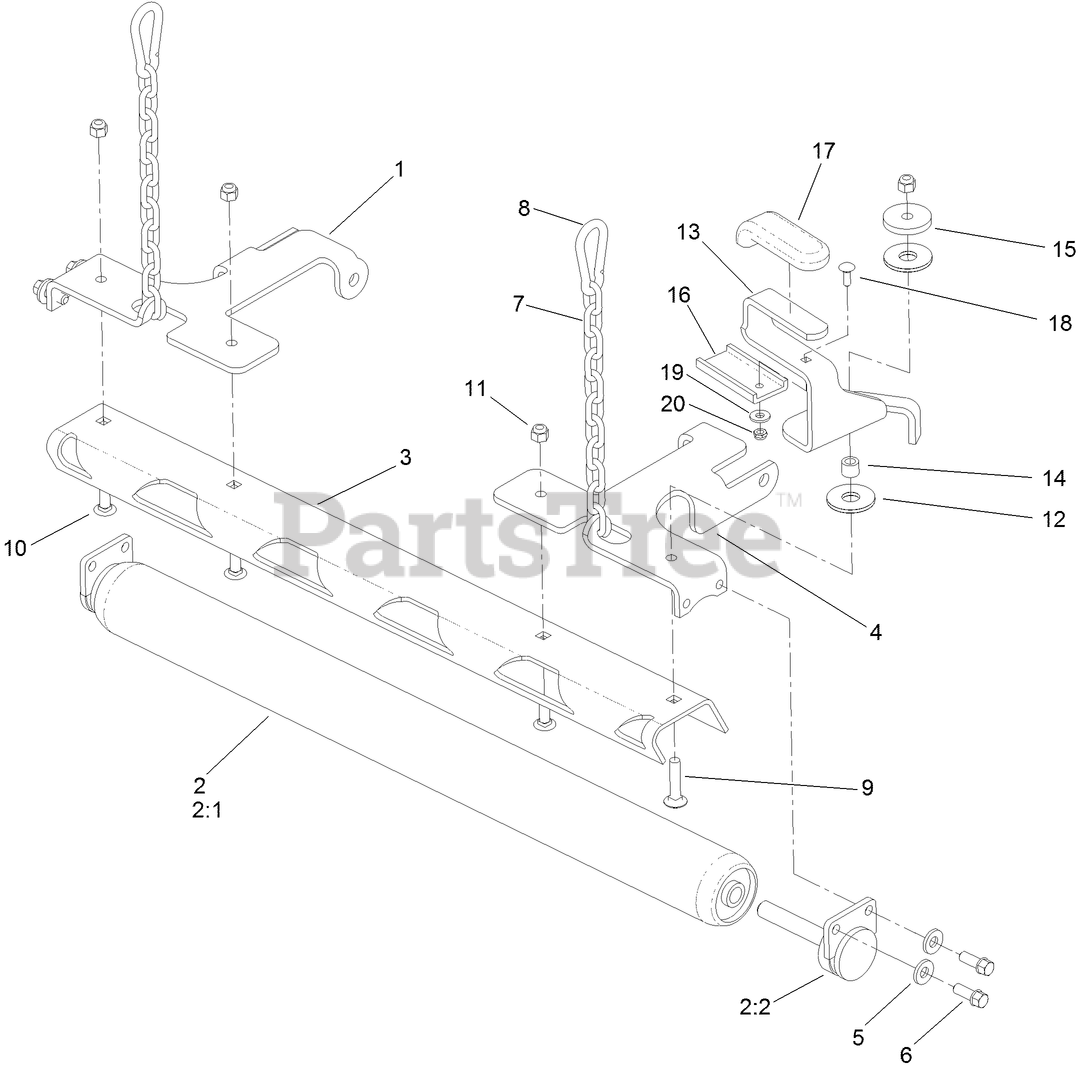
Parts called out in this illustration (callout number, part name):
1	MOUNT-ROLLER, LH
2	ROLLER ASM
2:1	ROLLER-STRIPER
2:2	HUB ASM
3	SCRAPER-ROLLER
4	MOUNT-ROLLER, RH
5	WASHER-BELLEVILLE
6	SCREW-HWH
7	CHAIN-STRAIGHT, LINK
8	LINK-SNAP
9	SCREW-CARR
10	SCREW-CARR
11	NUT-LOCK, NI
12	WASHER-FRICTION, COMPOSITE
13	HANDLE-ROLLER
14	BUSHING-LEVER, LIFT
15	WASHER-PLAIN
16	SLIDE-PLASTIC
17	GRIP-LEVER
18	BOLT-CARR
19	WASHER-FLAT
20	NUT-LOCK, NI
